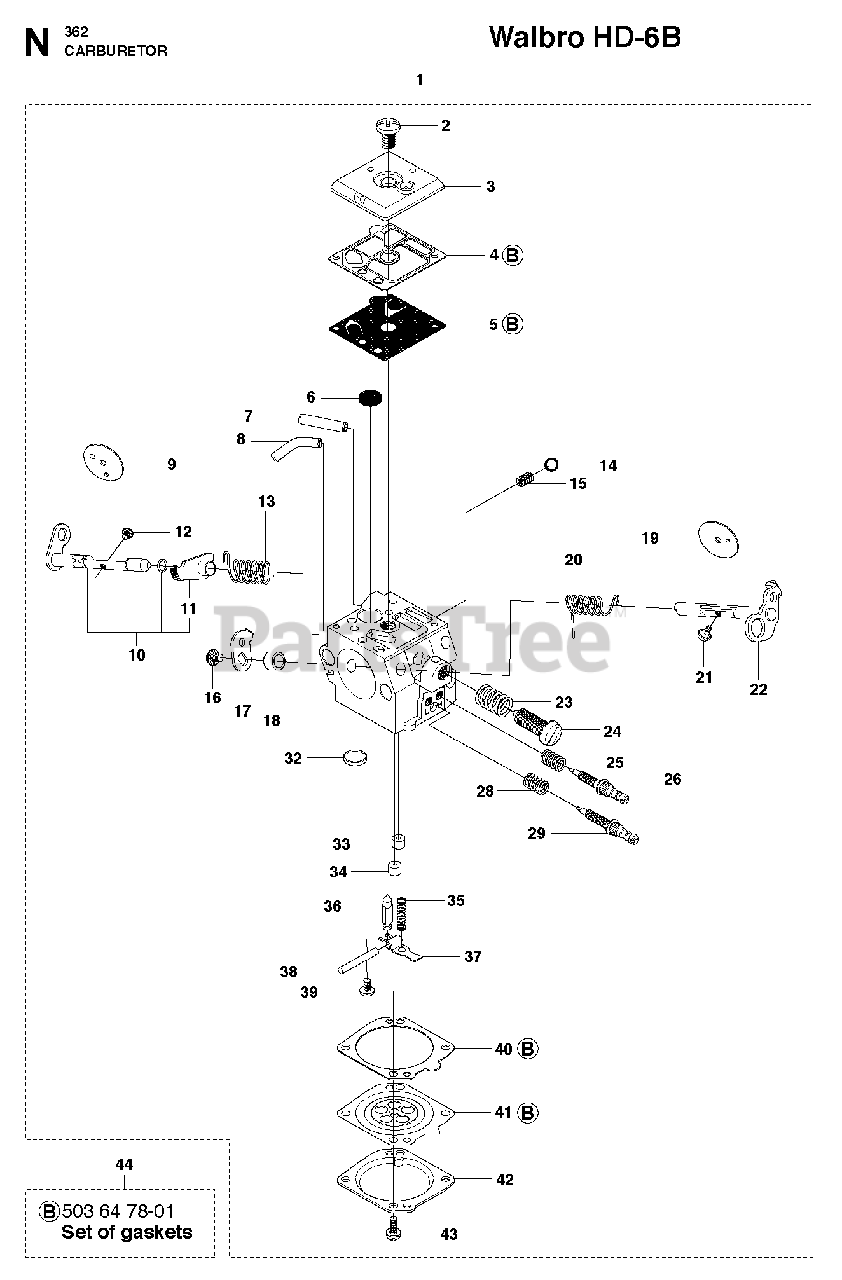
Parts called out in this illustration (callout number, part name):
1	CARBURETOR WALBRO HD-6B
4	GASKET, PUMP SIDE
5	PUMP DIAPHRAGM
6	FUEL INLET SCREEN
9	CHOKE FLAP
10	CHOKE SHAFT
11	LEVER
19	THROTTLE FLAP
21	SCREW SHUTTERS
23	SPRING
29	IDLING SCREW
32	WELCH PLUG
36	INLET NEEDLE
38	FULCRUM PIN
40	GASKET
41	GASKET
42	IMPULSE COVER
43	RP SCREW W/ WASHER
44	GASKET SET
